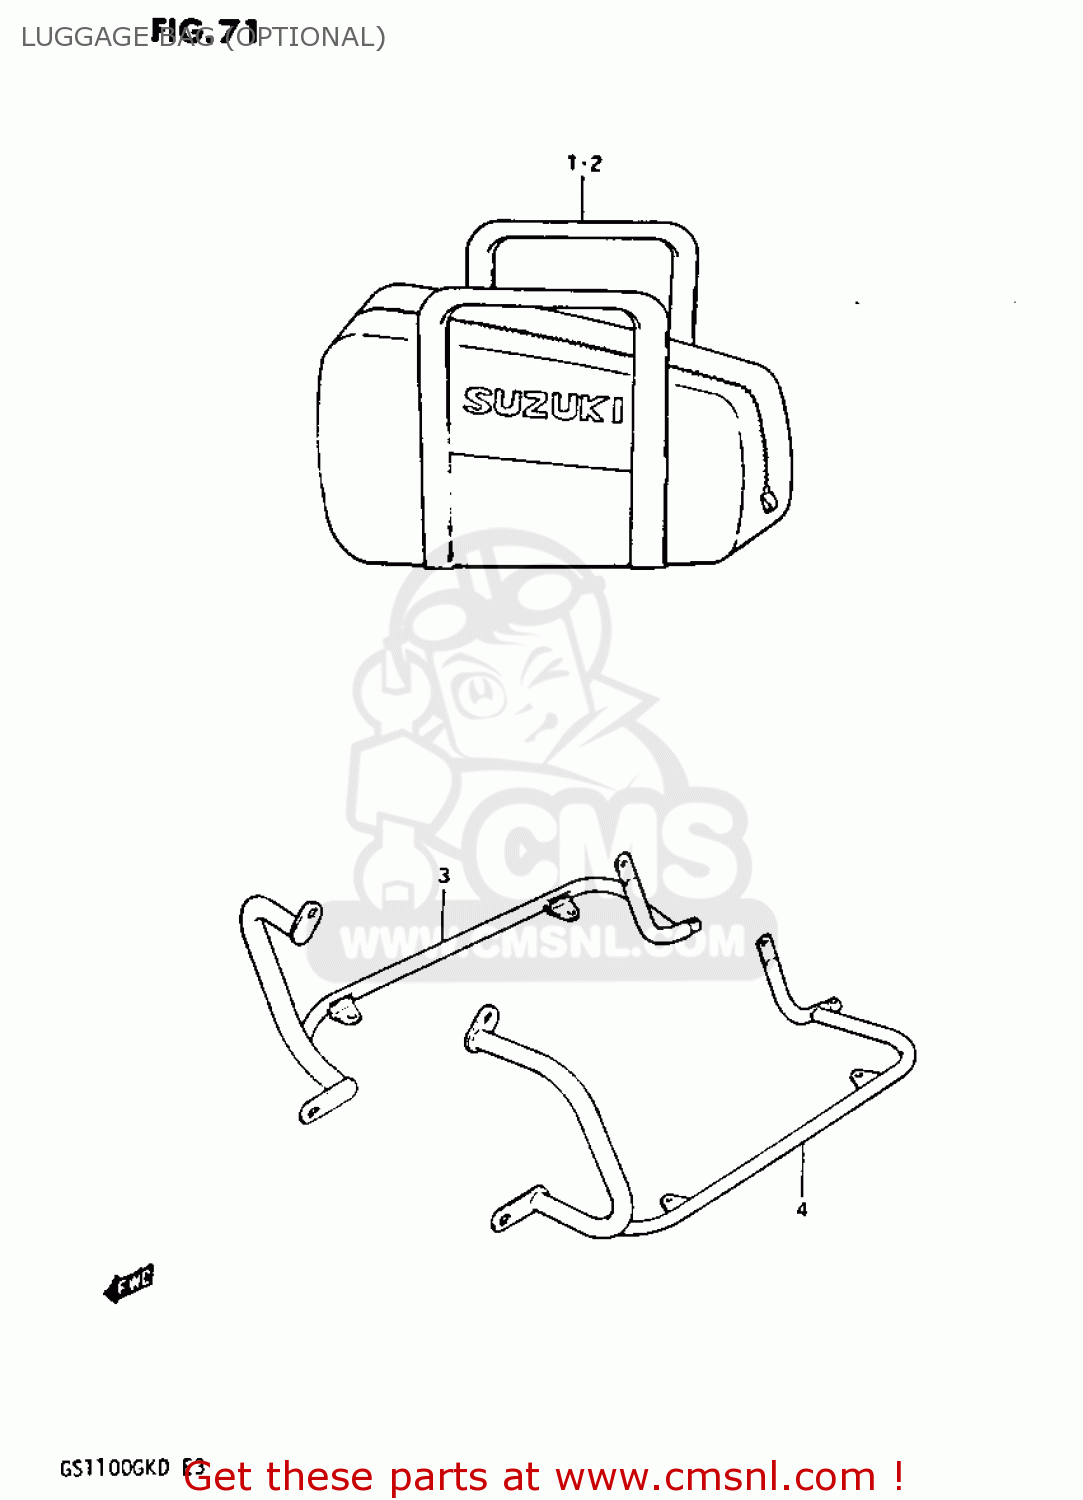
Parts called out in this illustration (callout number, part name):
1	LUGGAGE BAG RH
2	LUGGAGE BAG LH
3	CARRIER,REAR SIDE,RIGHT
4	CARRIER,REAR SIDE,LEFT
